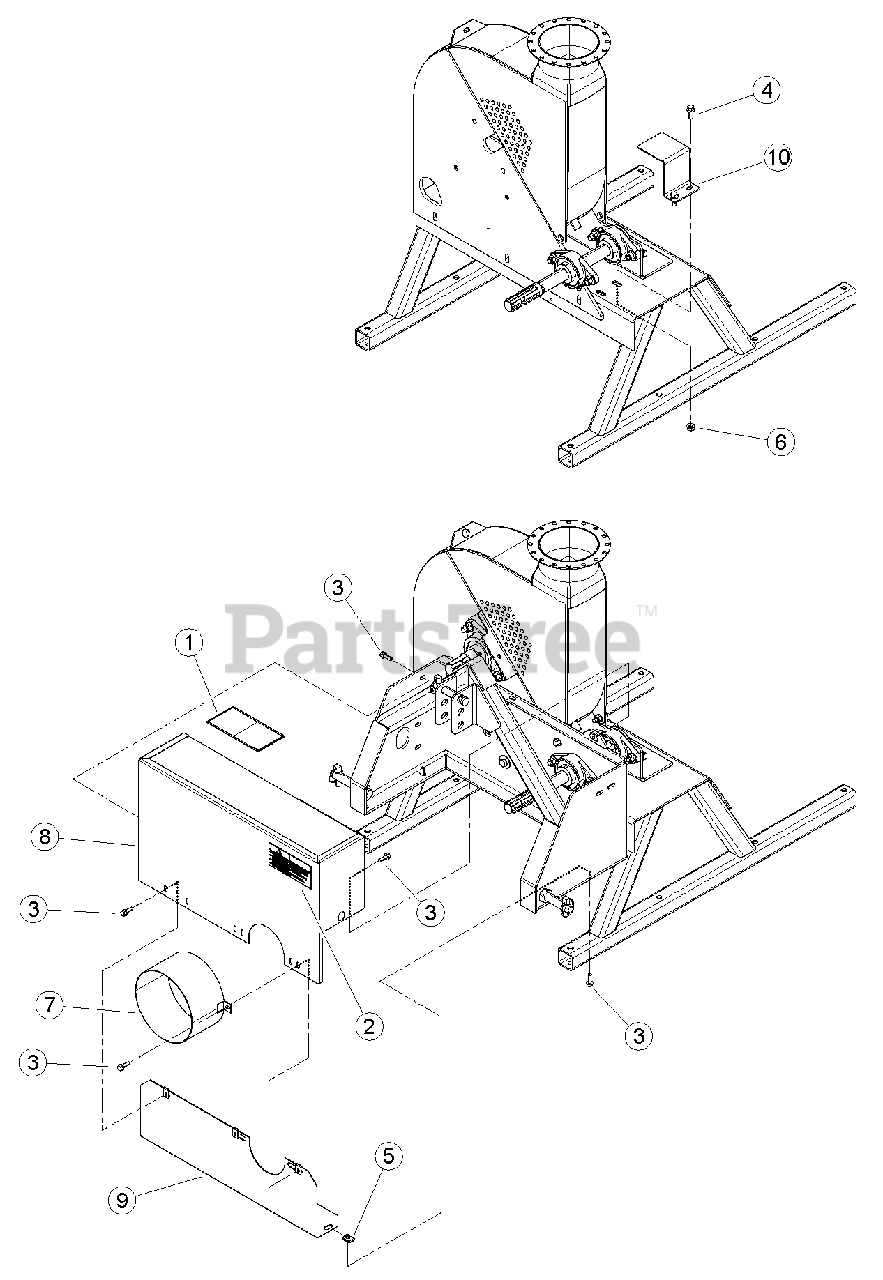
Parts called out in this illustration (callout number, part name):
1	DECAL, PTO DANGER ISO
2	DECAL, MULTILINGUAL MANUAL
3	BOLT, 5/16 X 1 FLANGE NC
4	BOLT, 3/8 X 1 FLANGE NC
5	NUT 5/16"-18 TINNERMAN U-TYPE
6	NUT, 3/8-16 NYLOCK FLANGE
7	WELDMENT, PTO SHIELD
8	WELDMENT, UPPER BELT GUARD
9	GUARD, LOWER BELT
10	COVER, JACKSHAFT
